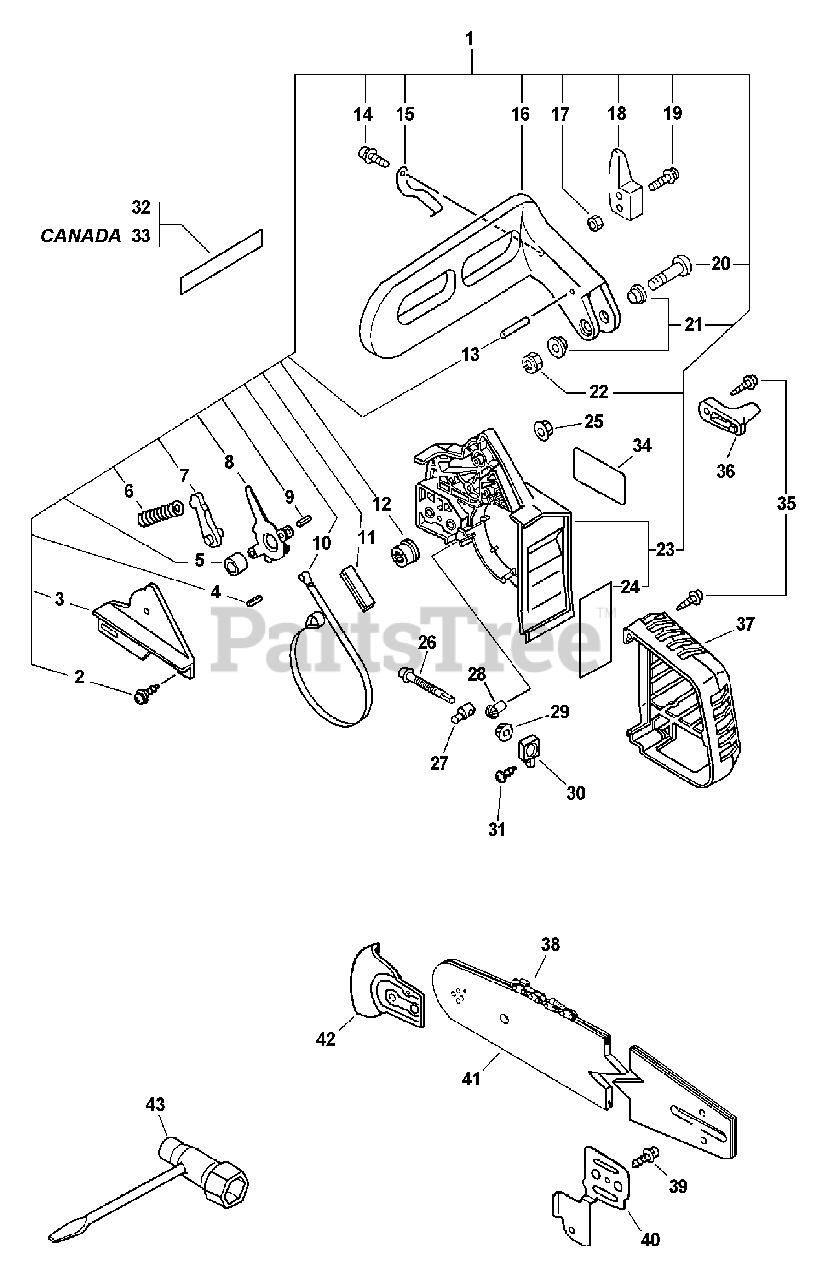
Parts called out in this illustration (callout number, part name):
1	CHAIN BRAKE ASSY
2	SCREW 4×12
3	COVER, BRAKE
4	PIN, SPRING 2.5×12
5	SPACER 8×12×9
6	SPRING, COMPRESSION
7	STOPPER, BRAKE
8	LEVER, BRAKE
9	PIN, SPRING 4×8.8
10	BAND, BRAKE
11	SEAL, BRAKE
12	ADJUSTER, BRAKE
13	ROLLER 4×23.8
14	SCREW 4×12
15	SPRING, FLAT
16	LEVER, BRAKE
18	WEIGHT, BRAKE
19	SCREW 4×22
20	SCREW 5×32
21	COLLAR 5.3×10×13×L5
22	NUT, LOCK M5
23	GUARD, SPROCKET - GRAY
24	SHIELD, HEAT 35×60×0.10
25	NUT, FLANGE M6
27	TENSIONER, CHAIN
28	GEAR, BEVEL
29	GEAR, BEVEL
30	COLLAR 8
31	SCREW 4×12
32	LABEL - BAR & CHAIN
33	LABEL, BAR & CHAIN
34	LABEL, MODEL
35	SCREW, TAPPING 5×20
36	CHAIN CATCHER
37	COVER, MUFFLER
38	SAWING CHAIN - 12" -- XTRAGUARD
38	SAW CHAIN 14" XTRAGUARD
38	SAW CHAIN 16"
39	SCREW 4×10
40	PLATE, GUIDE
41	GUIDE BAR, 12" DOUBLE-GUARD
41	GUIDE BAR, 14" DOUBLE-GUARD
41	GUIDE BAR, 16" DOUBLE-GUARD
42	KICK GUARD KIT
43	T-WRENCH 10×19 MM
